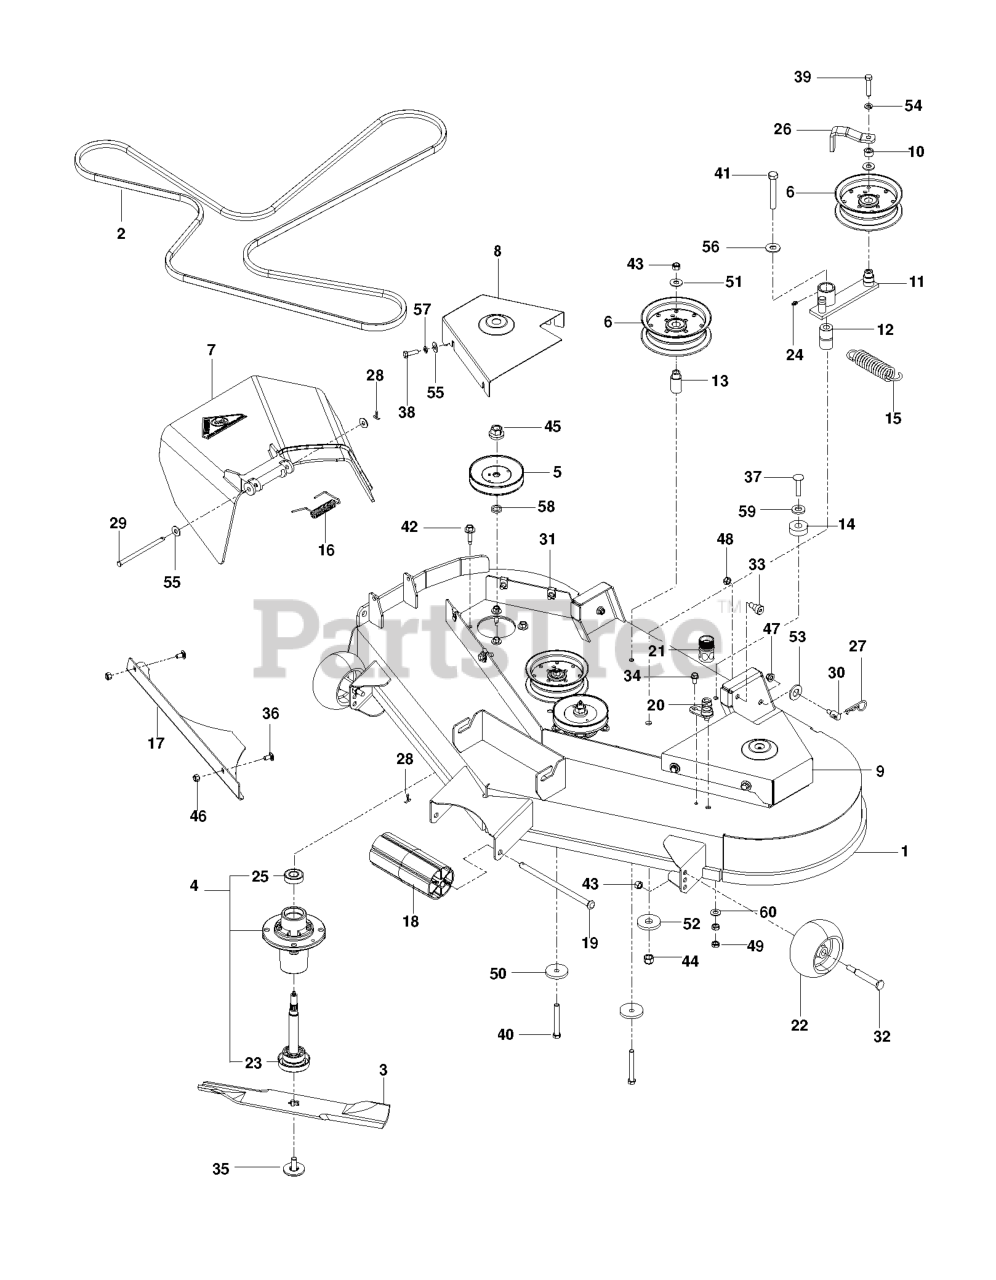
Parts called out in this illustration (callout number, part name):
1	DECK SVC W/DECALS RZ 48" KIT
2	BELT, DECK
3	BLADE, 16-1/4"
4	MANDREL.DECK.ASSEMBLY
5	PULLEY
6	PULLEY, IDLER
7	DISCHARGE CHUTE 48"
8	BELT SHIELD - R.H. ORANGE
9	BELT SHIELD - L.H. ORANGE
12	PIVOT BUSHING
13	IDLER BUSHING
14	ISO-MOUNT BUSHING
16	SPRING - TORSION
17	CONFINEMENT PLATE 48" BLK
18	NOSE ROLLER 48"
19	ROD.ROLLER.NOSE.NARROW.48"
20	PORT.WASHOUT
21	COUPLING.QUICK CONNECT
22	GAUGE WHEEL
23	GREASABLE MANDREL SHAFT
24	ZERK
25	BEARING, BALL
26	GUIDE, BELT
27	HAIRPIN #4
28	RP_COTTER PIN 1/8 X 3/4
29	PIN-CLEVIS 5/16 DIA X 5.19 ZD
30	STUD.FASTNER.W/ANTI-ROTATE
31	U-CLIP 5/16-18 NUT RETAINER
32	BOLT, SHOULDER
33	SB 3/8-16 X 3/8 SKT HD ZD
34	BOLT 1/4-20 X 1/2 HWST
35	BOLT.WASHER.ASM.7/16-2
36	CARRIAGE BOLT 5/16C X 5/8"
37	RHSNB 3/8-16X1-3/4
38	BOLT.FIN.HEX.5/16-18UNC X 1.00
39	HCS 3/8-16 X 1 3/4 GR5
40	BOLT.HEX.FIN.3/8-16 X 3.GR5
41	HCS 1/2-13 X 3-1/4 GD 5 ZD
42	WASHER HEAD SCREW
43	NUT
44	NUT.LK.W/WSH.1/2.
45	LOCKNUT - 9/16
46	NUT.71038.31-18.HEX.NYLOCK
47	5/16-18 NYLOC FLANGE NUT
48	NUT HEX 3/8-16 NYLON, THIN
49	NUT 3/8-16 HEX JAM
50	SPINDLE WASHER
51	RP WASHER 3/8 FLAT
52	WASHER, SUPPORT
53	WASHER
54	LOCKWASHER
55	WASHER.5/16.FLAT.STE.STD.
56	WASHER 1/2 FLAT
57	WASHER.LOCK.HVY.HLCL.SPR.5/16
58	WASHER-SPACER
59	WASHER 1/2" FLAT
60	WASHER
